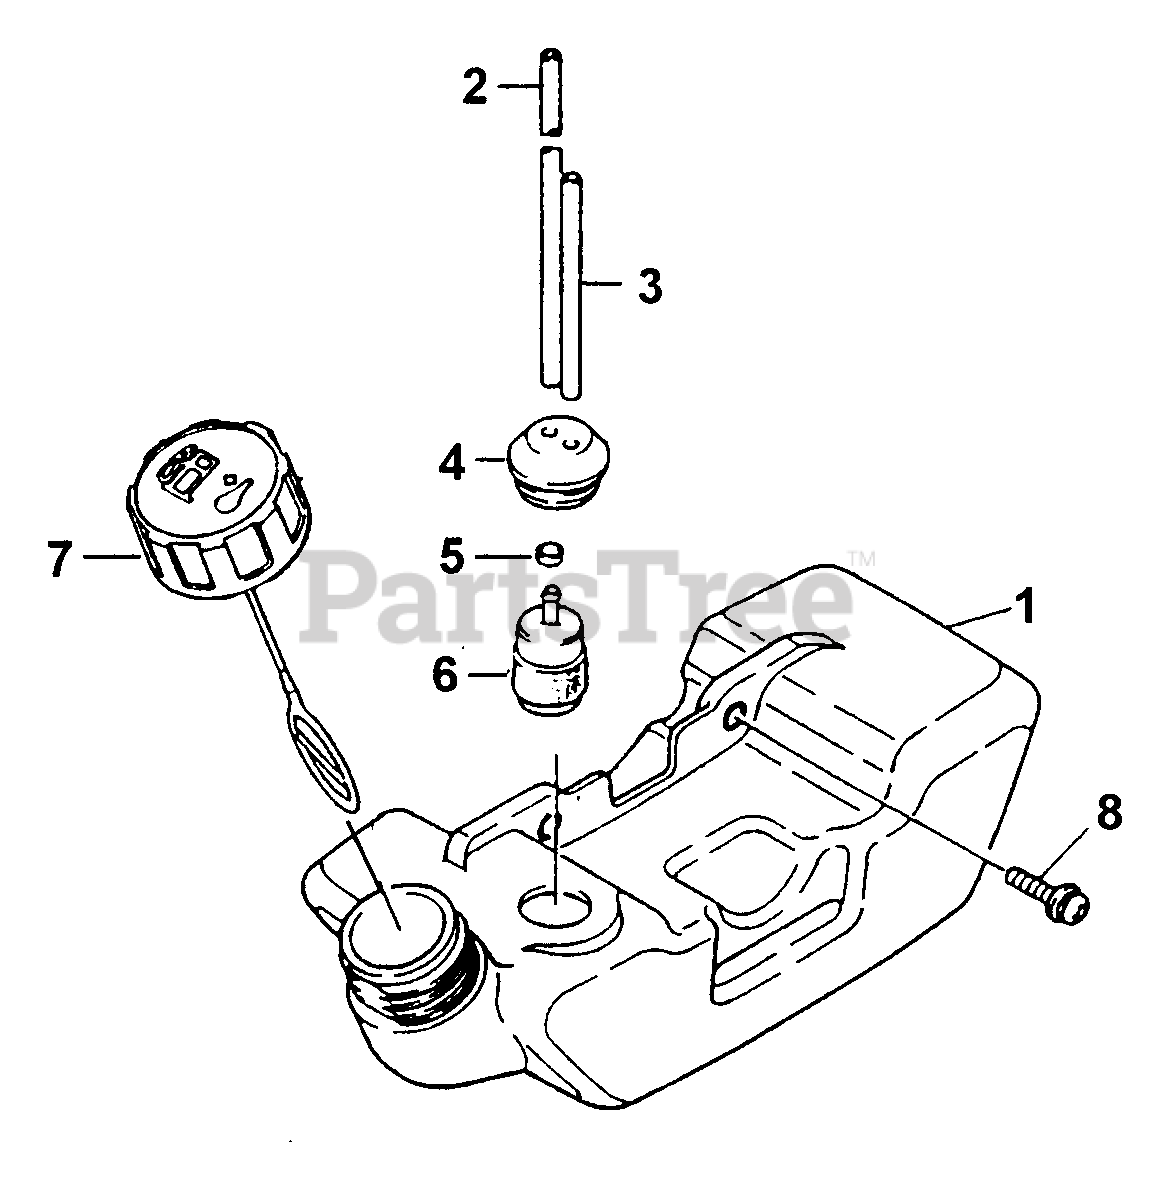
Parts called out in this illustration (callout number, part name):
1	FUEL TANK ASSY
2	TUBE, FUEL
3	TUBE, FUEL
5	BUSHING
6	FILTER, FUEL
7	TANK CAP
8	SCREW & WASHER
